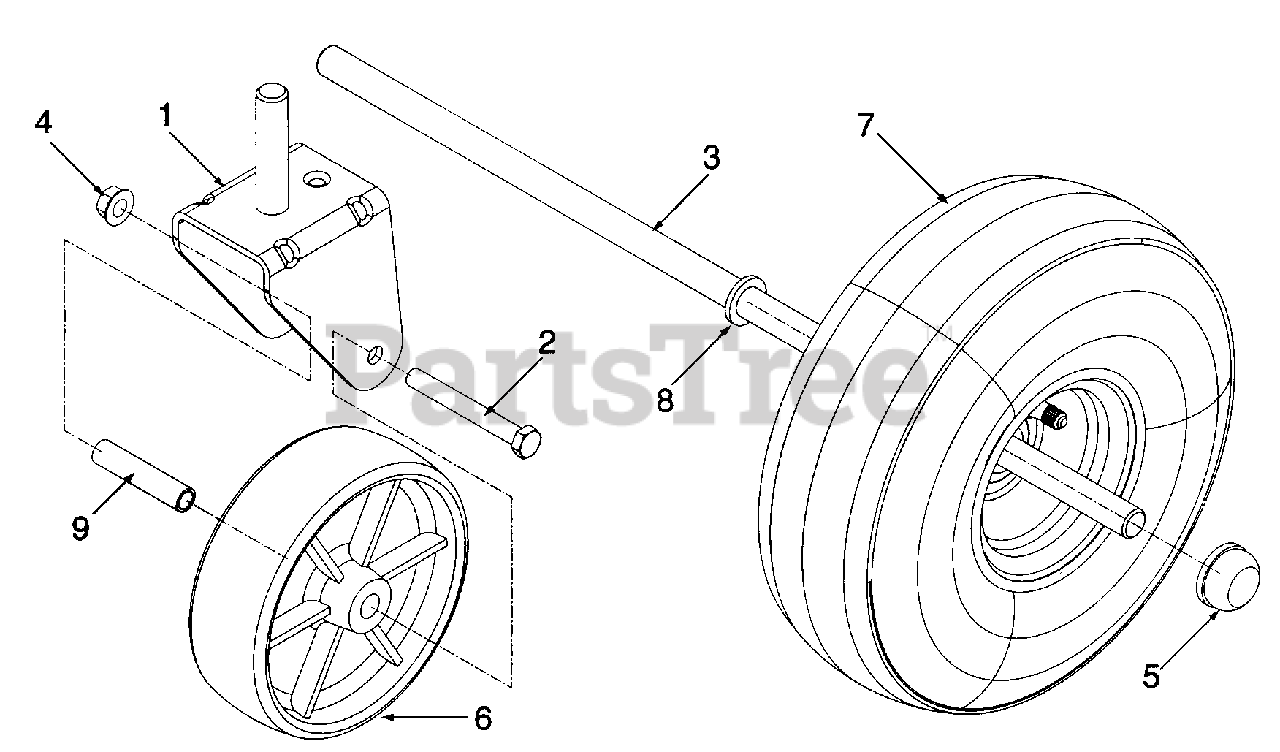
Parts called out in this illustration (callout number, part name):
2	Screw, Hex Cap, 3/8-16 x 3.0
3	Shaft, Rear Axle
4	Nut, Hex Flange Lock, 3/8-16
6	Wheel, 6.00 x 2.00
7	Wheel Assembly, Complete, 10 x 4 x 4
8	Washer, Flat, .64 x 1.12 x .12
9	Spacer, .384 ID x .5 OD x 2.3 Lg
